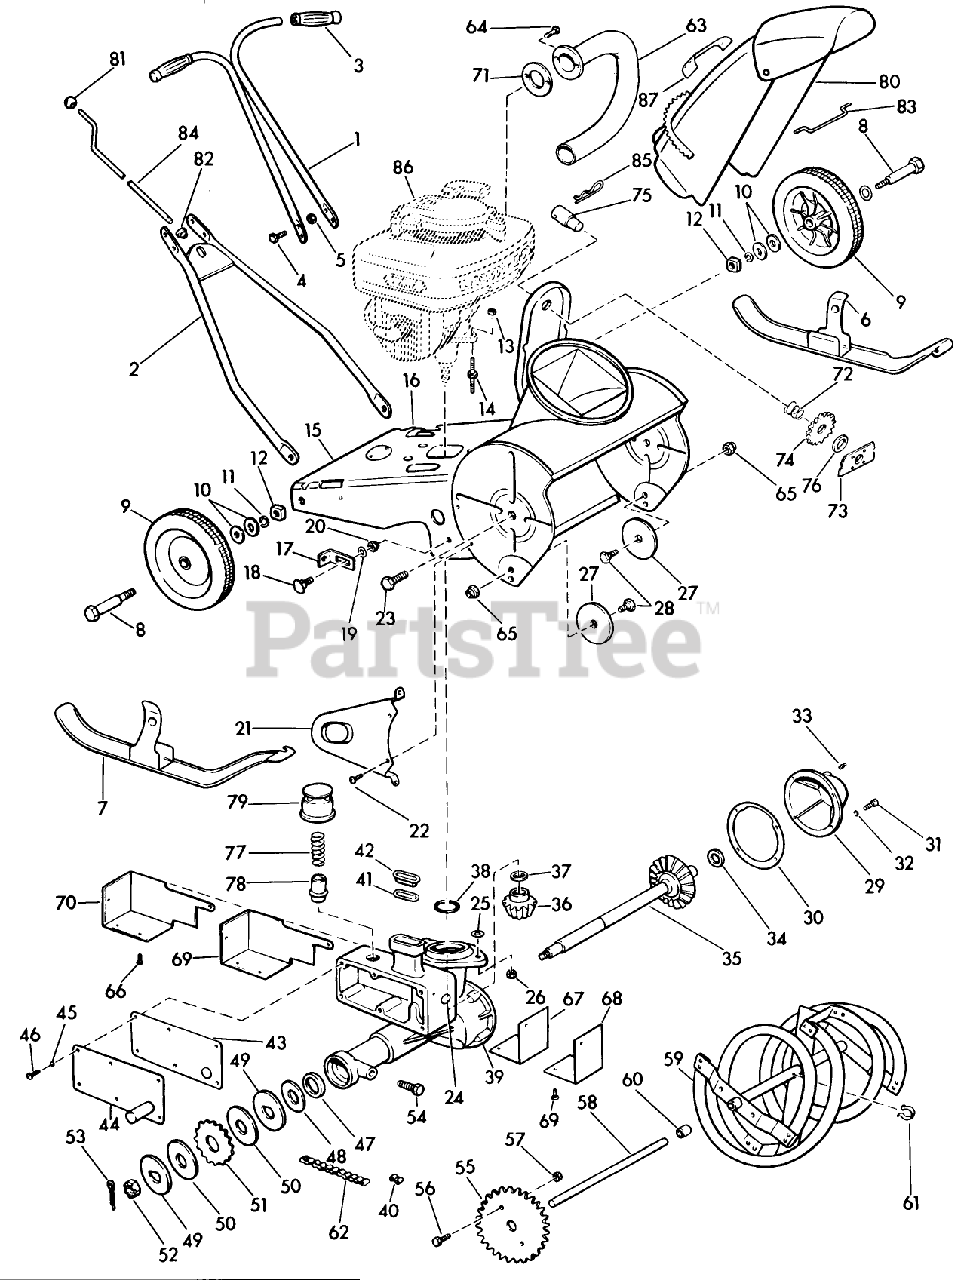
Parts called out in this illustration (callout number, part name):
5	STOP NUT
9	Wheel Assembly-Rear
10	WASHER WROUGHT
11	WASHER, LOCK
15	Base, Housing and Bracket Assembly
20	Nut-Huglok
24	Plug-Core
25	Washer-G-case to Base Stud
28	Stud-Front Wheel
29	Cover-Gearcase
31	Screw-Gearcase Cover
34	Thrust Washer-Driveshaft Gear
35	Driveshaft and Gear Assembly
37	Thrust Washer-Pinion Gear
38	O Ring-G-case to Crankcase
40	Liner-Muffler to Cylinder
49	Washer-Steel "D" Hole
53	Cotter Pin-Wheel
54	Screw-Stabilizer Bracket
57	Nut-Huglok
86	Lawn Boy Engine-C-17AA
87	Decal-Oil Instruction
